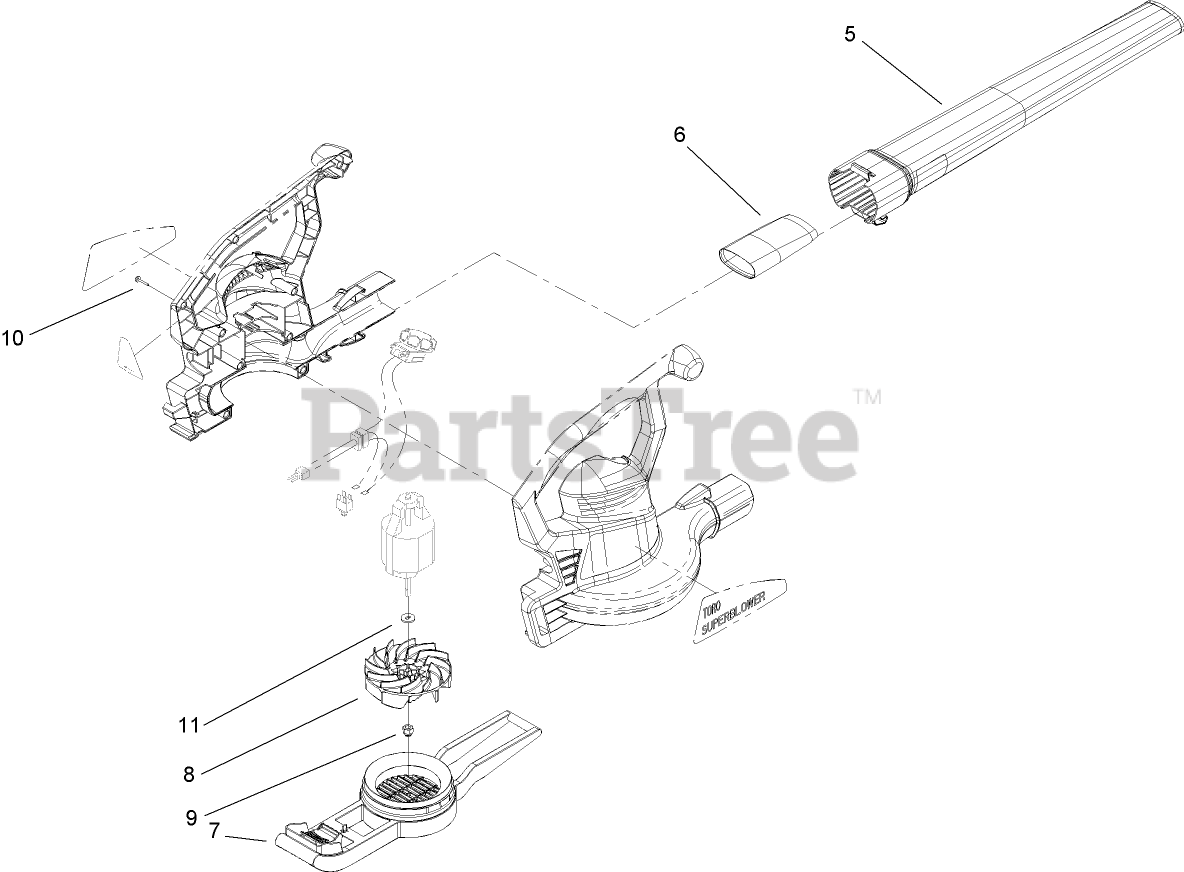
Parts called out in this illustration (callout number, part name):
6	TUBE-INSERT
8	IMPELLER-BLOWER
10	SCREW-PPH
11	WASHER-FLAT
